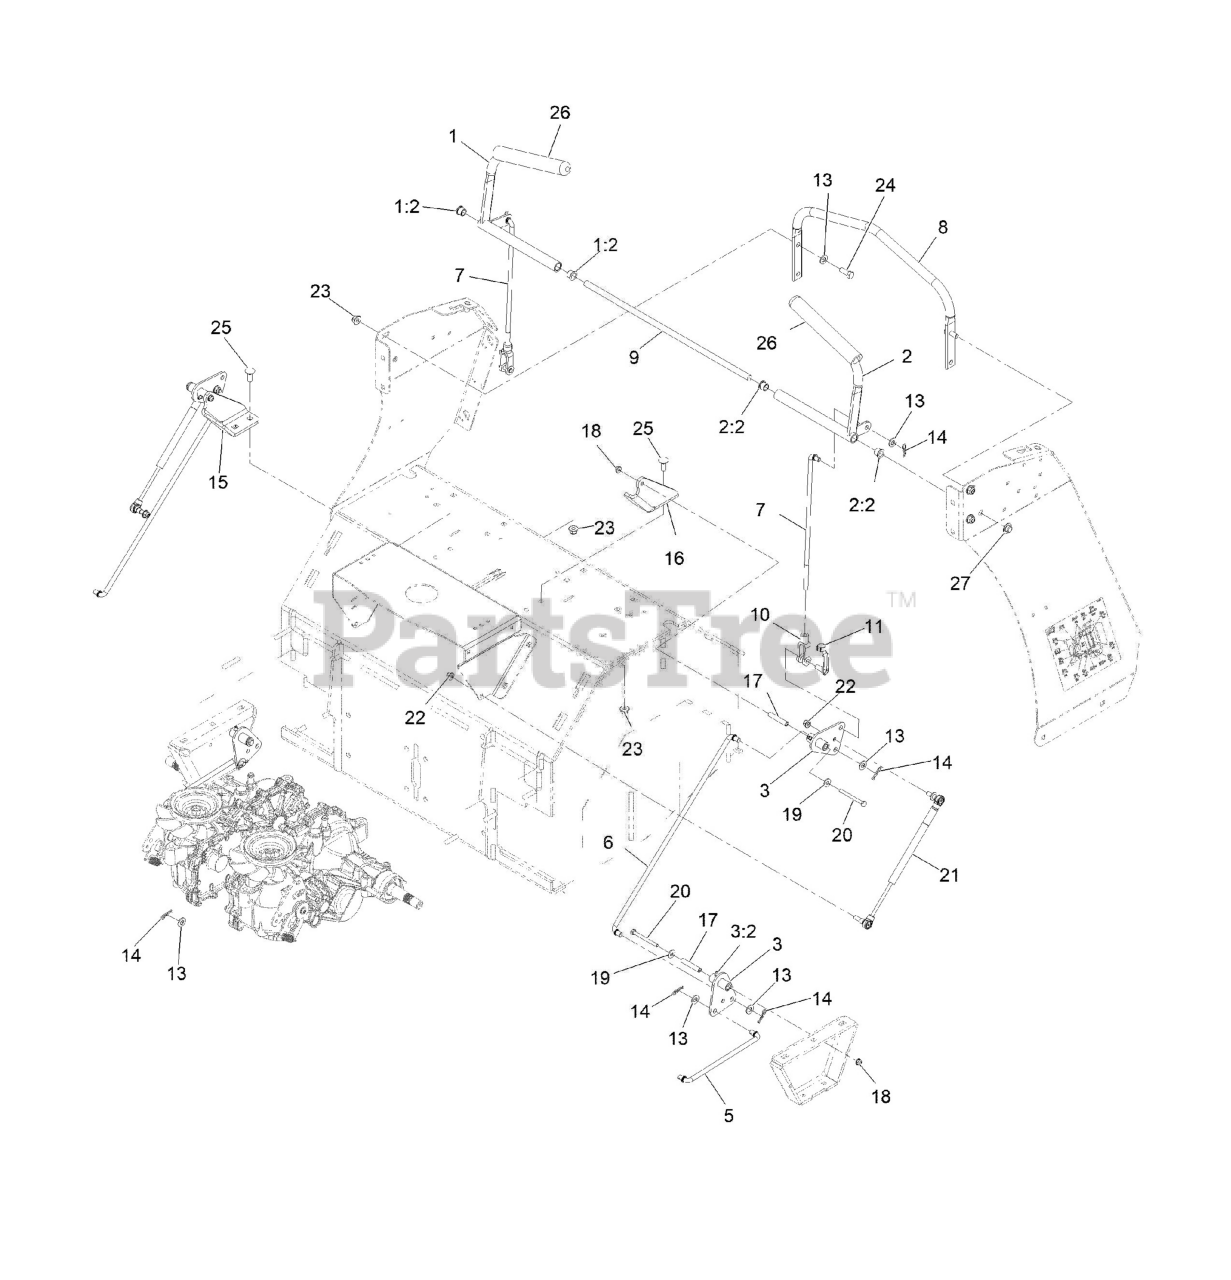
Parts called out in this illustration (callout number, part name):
1	RH CONTROL HANDLE ASM
1:2	BEARING-FLANGE
2	LH CONTROL HANDLE ASM
2:2	BEARING-FLANGE
3	CRANK-BELL
3:2	FITTING-GREASE
5	LINK-CONTROL, HYDRO
6	LINK-CONTROL, BELL CRANK
7	LINK-CONTROL, BELL CRANK
8	BAR-REFERENCE
9	SHAFT-PIVOT, CONTROL
10	YOKE-LINKAGE, BRAKE
11	PIN-SPRING, CLEVIS
13	WASHER-FLAT
14	PIN-COTTER
15	BRACKET-PIVOT, RH
16	BRACKET-PIVOT, LH
19	WASHER-FLAT
20	SCREW-HH
21	DAMPER-CONTROL, MOTION
22	NUT-HF, NI
23	NUT-HF, NI
24	SCREW-HH
25	BOLT-CARR
26	GRIP-LEVER, CONTROL
27	NUT-PUSH
